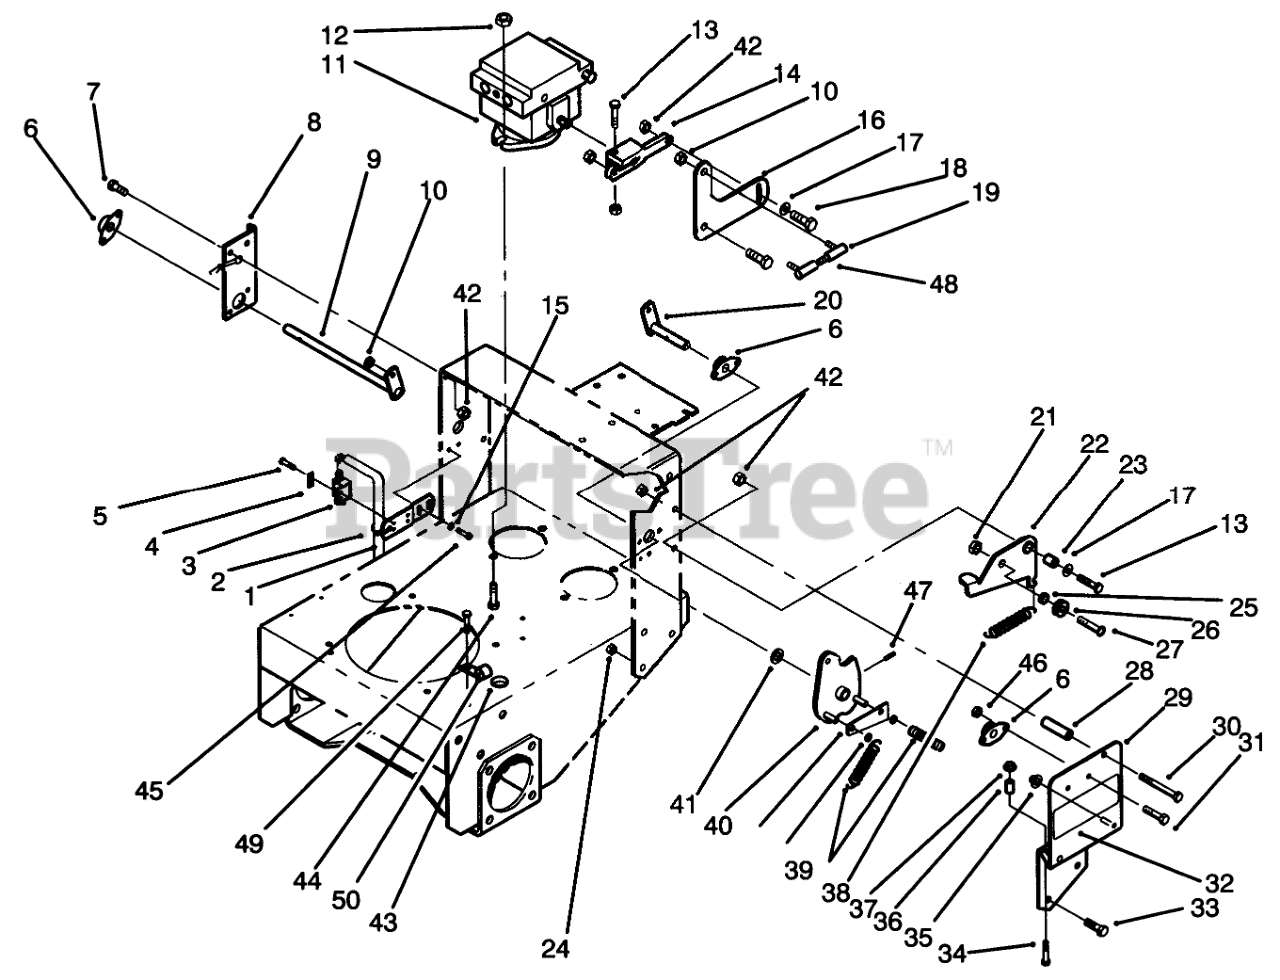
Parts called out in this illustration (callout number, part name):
1	NEUTRAL BRACKET B
2	TIE-CABLE
3	SWITCH-POLE, SINGLE
4	PLATE-SWITCH
5	SCREW-TAPTITE
6	SIDE FLANGE BEARING ASM
7	SCREW-HH
8	Bracket-Bushing
9	RH LEVER WA
10	NUT-LOCK, NI
11	HYDRAULIC PUMP
12	NUT-HF
13	SCREW-HH
14	ARM-PUMP
15	WASHER-FLAT
16	FOLLOWER ARM B
17	WASHER-PLAIN
18	SCREW-HH
19	JOINT-BALL
20	LH LEVER WA
21	NUT-LOCK, NI
22	Detent Arm Assembly L.H.
23	BUSHING-ARM, DETENT
24	NUT-LOCK, NI
25	SPACER-BEARING
26	BEARING-BALL
27	SCREW-HSBH
28	STOP-REVERSE
29	LEFT BRACKET WA R
30	SCREW-HH
31	SCREW-HH
32	DECAL-HYDRO
33	SCREW-HH
34	SCREW-HH
35	NUT-PUSH
36	SPACER-TUBULAR
37	NUT-LOCK, HHF
38	SPRING-DETENT
39	SPRING-EXTENSION
40	Pivot Assembly L.H.
41	WASHER-THRUST
42	NUT-LOCK, NI
43	GROMMET
44	SCREW-HH
45	Screw
46	NUT-LOCK, NI
47	PIN-ROLL, SLOTTED
48	BALL JOINT ROD
49	SCREW-HWH
50	CLAMP-R
